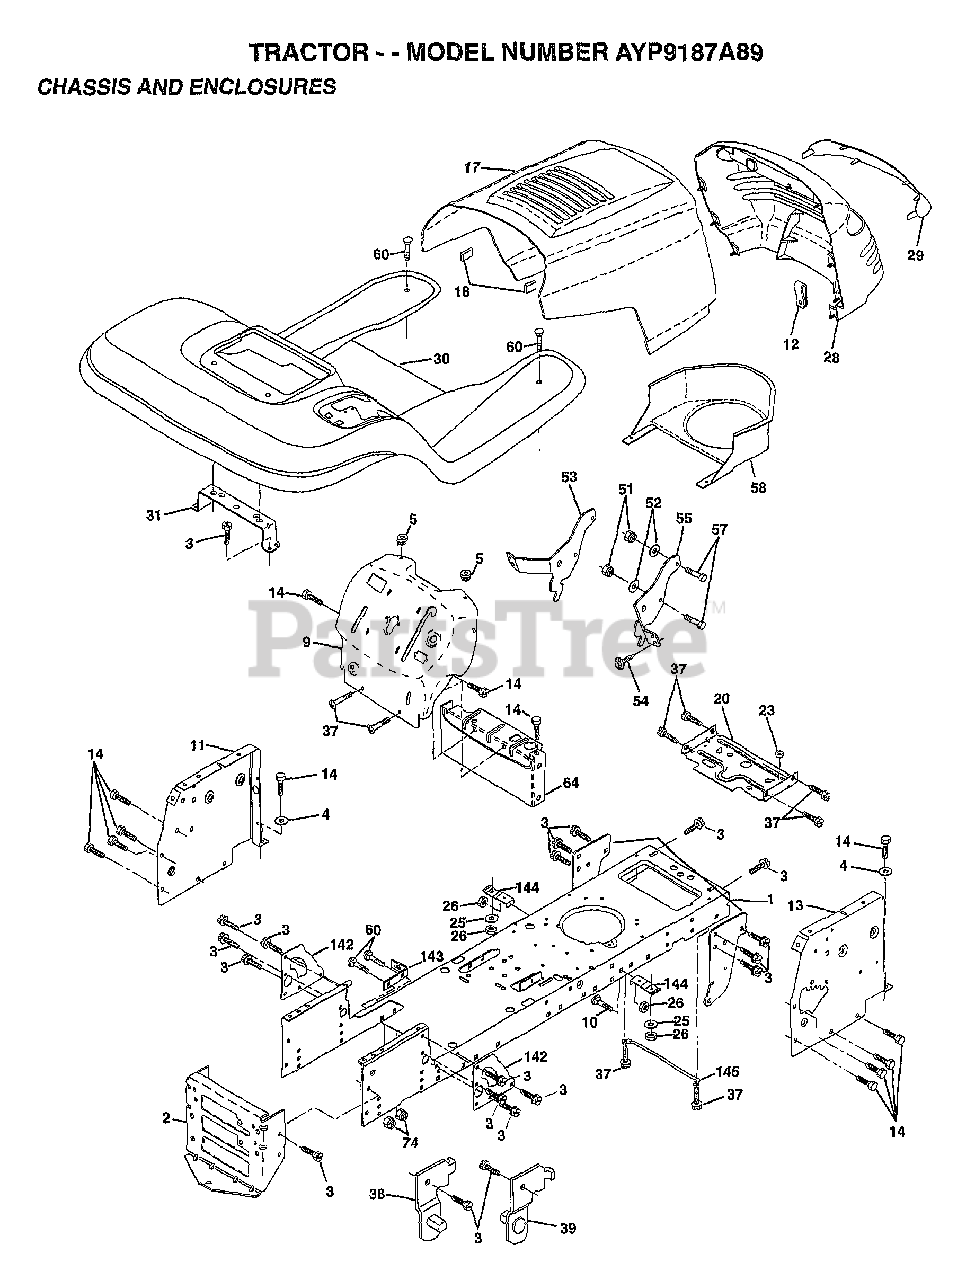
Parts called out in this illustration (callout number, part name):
1	CHASSIS
3	SCREW
4	WASHER
5	BUMPER-HOOD/DASH
11	"PANEL-DASH,LH"
12	CLIP.TINNERMAN
13	"PANEL-DASH,RH"
14	SCREW LT
17	HOOD.STEEL.ASSY
20	"PLATE-MTG,BATT/FU"
25	WASHER
26	NUT
28	GRILL
29	LENS.EURO.W/DECAL
30	FEND/FTREST PNT
31	BRACKET SUPT FEND
37	SCREW LT
38	BRACKET ASM LH
39	BRACKET ASM RH
51	NUT
52	WASHER
53	BRACKET.GRILLE.LH
54	SCREW.HEX.WS.HD
55	BRACKET.GRILLE.RH
58	AIR DUCT
60	BOLT
64	DASH-LOWER
140	BRKT SUSPENSION
142	PLATE.REINFORCEMT
143	"BRKT-S'BAR,CHASSI"
145	"ROD POVOT,CHASSIS"
